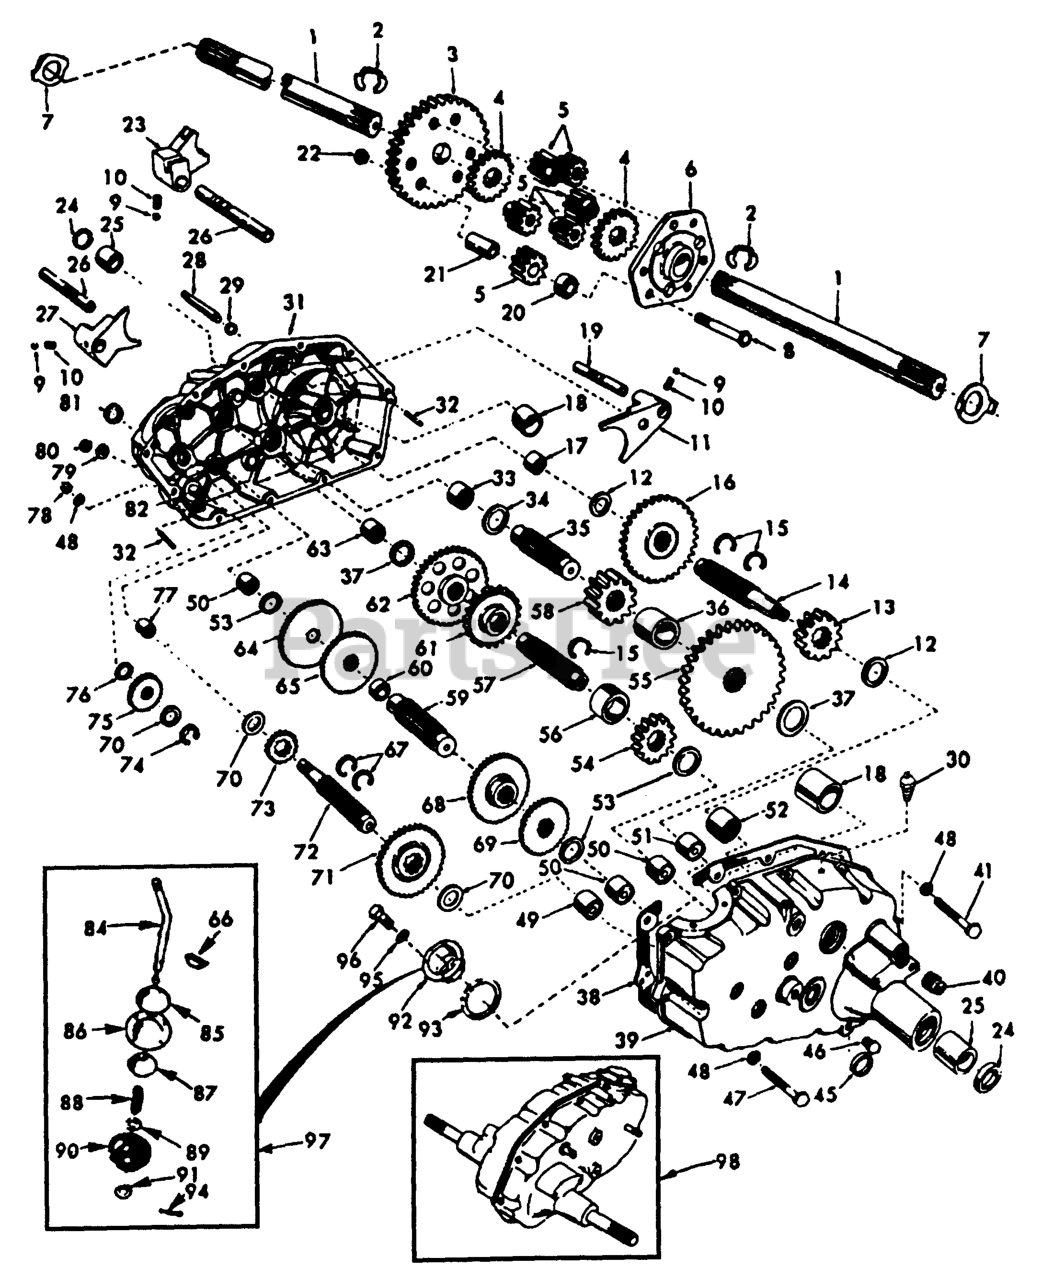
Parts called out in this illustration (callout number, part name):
1	AXLE SHAFT T
2	Retaining Ring
3	FINAL GEAR T
4	DIFF GEAR T
5	DIFF PINION T
6	DIFF CARRIER T
7	WASHER T
8	Bolt, Hex Head 3/8-24 x 3-1/4 (1" Thread Length)
9	STEEL BALL KIT
10	SPRING T
12	THRUST WASHER
13	RED PINION T
14	GEAR SHAFT T
15	SNAP RING T
16	GEAR T
18	BEARING
21	PINION RS
22	GRIPCO NUT
24	OIL SEAL STD
25	BRNG. T
26	SHAFT T
27	SHIFT FORK T
28	SHIFT SHAFT
29	SEAL.OIL.SHAFT.SHIFT.T
31	TRANSAXLE 6SP GT
33	NEEDLE BRNG T
34	WASHER RACE BEARING THRUST
35	GEAR SHAFT T
36	GEAR SPACER T
39	Gearcase and Bearings, L.H.
40	Pipe plug 1/2-14 N.P.T.
41	Bolt, Hex 5/16-18 UNC x 1-5/8
47	HEX BOLT
48	LOCKWASHER
49	BEARING TI
50	NEEDLE BRNG T
51	NEEDLE BRNG T
52	BEARING STD
53	BRNG RACE T
54	RED PINION T
55	RED GEAR T
56	PINION SPACER T
57	GEAR SHAFT T
58	FINAL PINION T
59	GEAR SHAFT T
61	RED PINION T
62	RED GEAR T
64	LOW SPEED GEAR T
65	GEAR.REVERSE.T
67	RING STD (1 2)
68	GEAR.SPEED.INTERMEDIATE.T/A
69	HIGH SPEED GEAR T
70	THRUST WASHER
71	CLUSTER GEAR T
72	INPUT SHAFT T
73	LO SPEED PINION T
74	RETAINING RING LT
75	IDLER GEAR T
78	NUT
80	NUT **
81	SEAL STD
82	SHAFT T
84	GEAR SHIFT LVR T
86	COVER AND PIN T
87	GUIDE BALL T
89	WASHER
90	SEAL.SHIFT
91	Washer 9/16 x 15/16 x 12 Gauge
92	GEAR SHIFT GATE T
94	COTTER PIN
95	WASHER.LOCK.HVY.HLCL.SPR.5/16
96	BOLT
97	GEAR SHFT LVR T
98	TRANSAXLE ASSY 6SP
